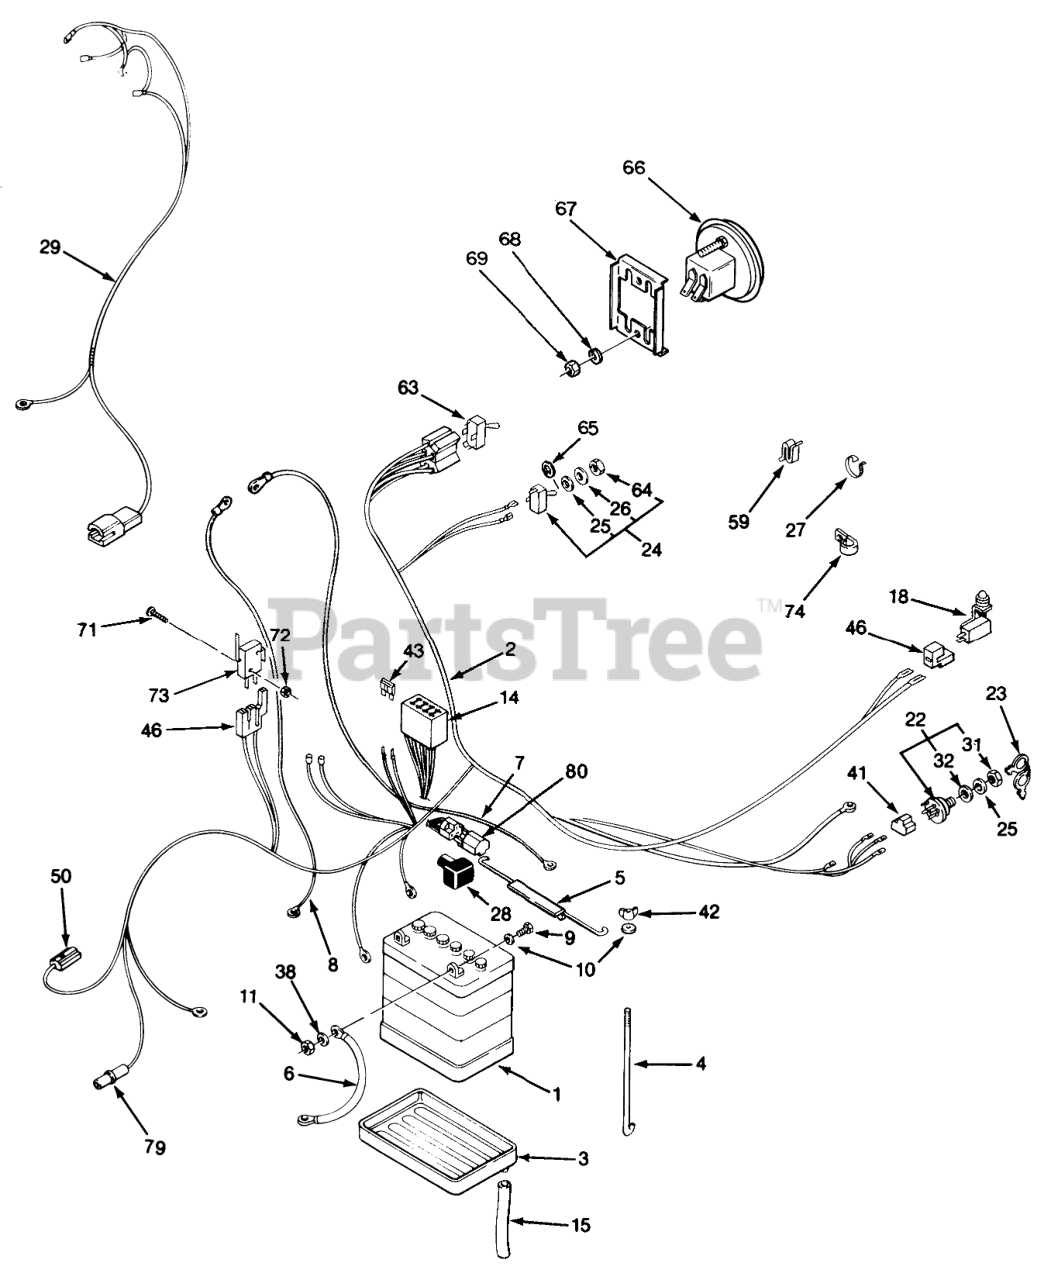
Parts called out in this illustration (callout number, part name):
1	Battery
2	Harness Wire (Incl. Ref. #14, 41 & 46)
3	TRAY-BATTERY
5	ROD-BATTERY HOLD DWN
7	WIRE - 14" BLACK
8	ASS'Y-WIRE
9	SCREW-HH
10	WASHER-FLAT
11	NUT-HEX
14	FUSE-HOLDER 4 WAY
15	TUBE-BATTERY DRAIN
18	SWITCH-SEAT
22	Switch-Ignition (Incl. Ref. #31-32)
23	Key
24	Switch-Light (Incl. Ref. #64 & 65)
25	Washer
26	Washer
27	PLASTIC TIE
28	Boot
29	HARNESS-HEADLIGHT
32	LOCKWASHER
38	WASHER-LOCK
41	CONNECTOR-5 WAY-SERV
42	NUT-WING
43	FUSE-BLADE, 15 AMP
46	CONNECTOR BODY
50	CONNECTOR BODY ELECT
59	SPEED CLIP
63	PTO-SWITCH W/COVER
65	TAB-WASHER
66	Hourmeter
67	CLAMP-HOUR METER
68	WASHER-LOCK
69	Nut
71	Screw
72	NUT HEX 4-40 ELAST
73	SWITCH - CLUTCH
74	CLAMP
79	SOCKET HOUSING
80	RELAY
